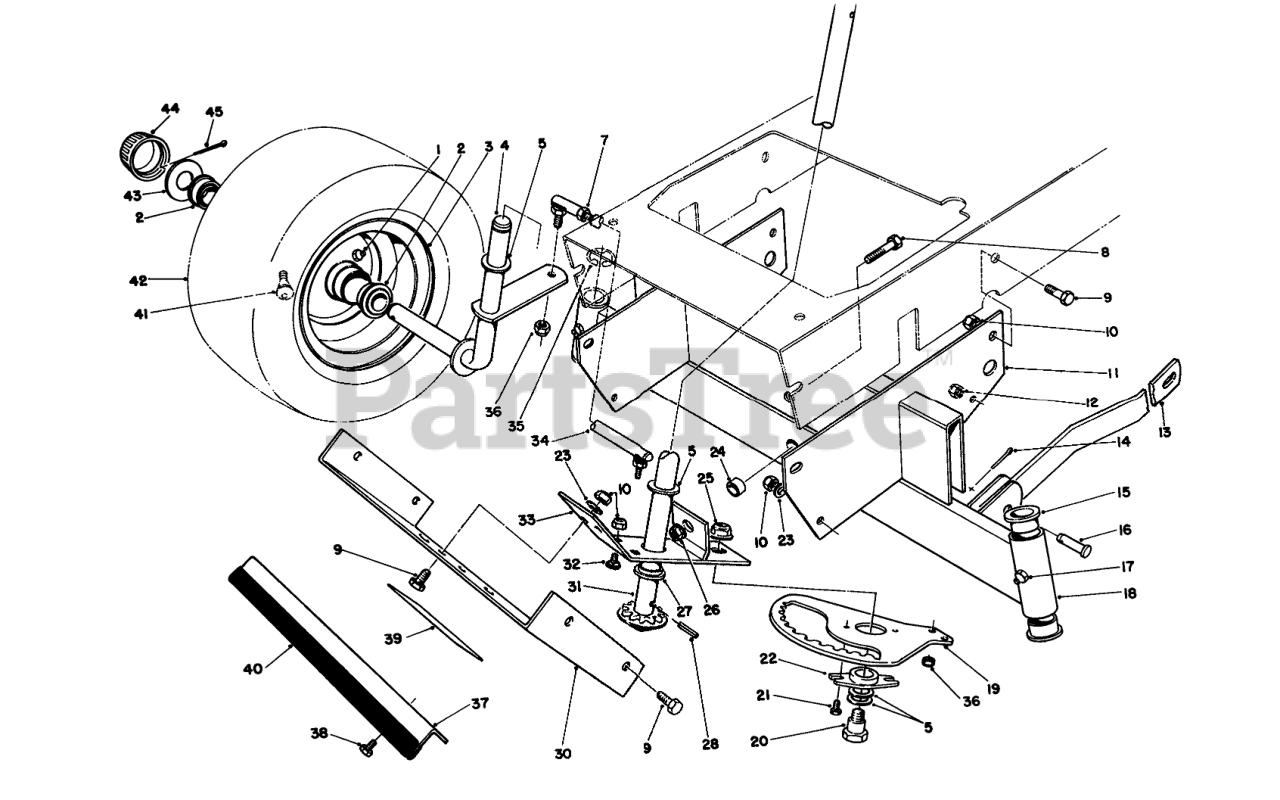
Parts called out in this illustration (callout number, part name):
1	FITTING-GREASE
2	Bearing
4	Spindle RH
5	WASHER-THRUST
7	NUT-JAM
8	SCREW-HH
9	SCREW-HH
10	NUT-LOCK, NI
11	Support
12	NUT-HEX
13	Arm-Suspension, Front
14	PIN-COTTER
15	BEARING-FLANGE
16	PIN-CLEVIS
17	GREASE FITTING
18	Axle-Front (Incl. Ref. #15 & 17)
19	Rack-Steering
21	SCREW-HWH
22	BUSHING-SECTOR
23	WASHER-PLAIN
24	SPACER-AXLE, FRONT
25	NUT-HF
26	NUT-HF
27	BEARING-FLANGE
28	PIN-ROLL, SLOTTED
30	Cover-Front
31	STRG SHAFT WA
32	SCREW-CARR
33	Bracket-Rack, Steering (Incl. Ref. #27)
34	Tie Rod-Adjustable (Incl. Ref. #7)
35	E-RING
36	NUT-LOCK
37	FRONT GUARD R
38	SCREW-HWHTF
39	Decal-Warning
40	TRIM-FRONT GUARD
41	STEM-VALVE
42	TIRE,PNEU.11X4.00X5
43	WASHER-PLAIN
44	CAP-HUB
45	PIN-COTTER
